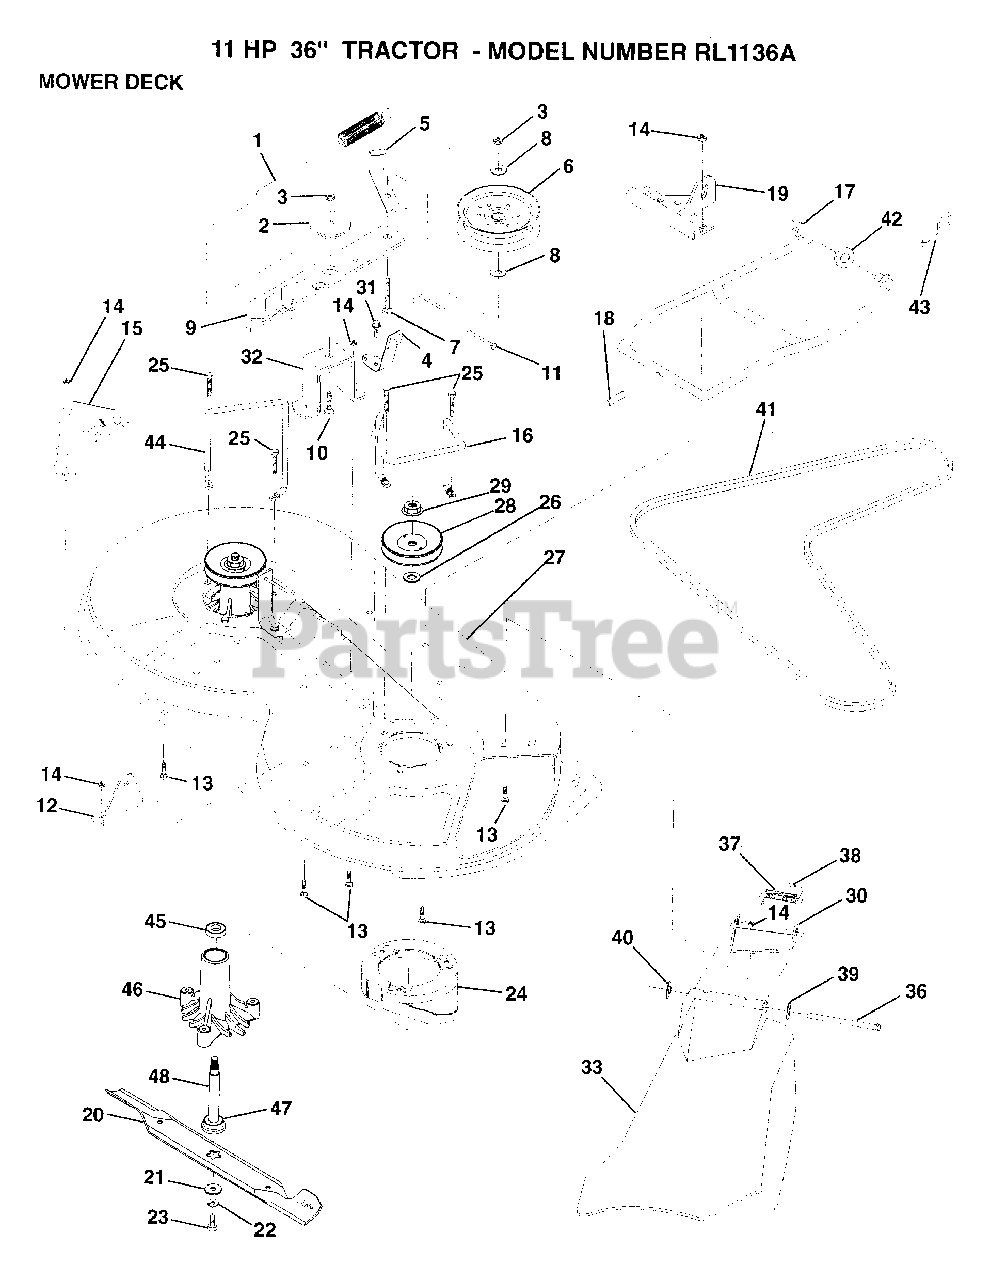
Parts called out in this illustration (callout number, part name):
2	SPACER RETAINER
4	BRAKE ASM
5	IDLER BELT GUIDE
6	PULLEY IDLER
7	BOLT
8	WASHER
10	BOLT D
11	BRAKE ROD
12	"BRKT,LIFT REAR"
13	BOLT
15	"BRKT,LIFT REAR LH"
17	MOWER LINK STAB
18	"PIN,GROOVE"
19	"BRKT,LINK STABILI"
20	"BLADE.36"" HIPERF"
21	WASHER BLADE
23	BLADE BOLT
26	WASHER
31	SCREW LT
32	"SUPT,IDLER ARM"
36	HINGE ROD
37	SPRING TORSION
38	CAP-SLEEVE LT
39	WASHER
40	NUT PUSH M
41	V-BELT.PRIM.78.5.
43	RETAINER.SPRING
45	BEARING
46	HSG ASM MANDREL
47	BEARING.BALL
